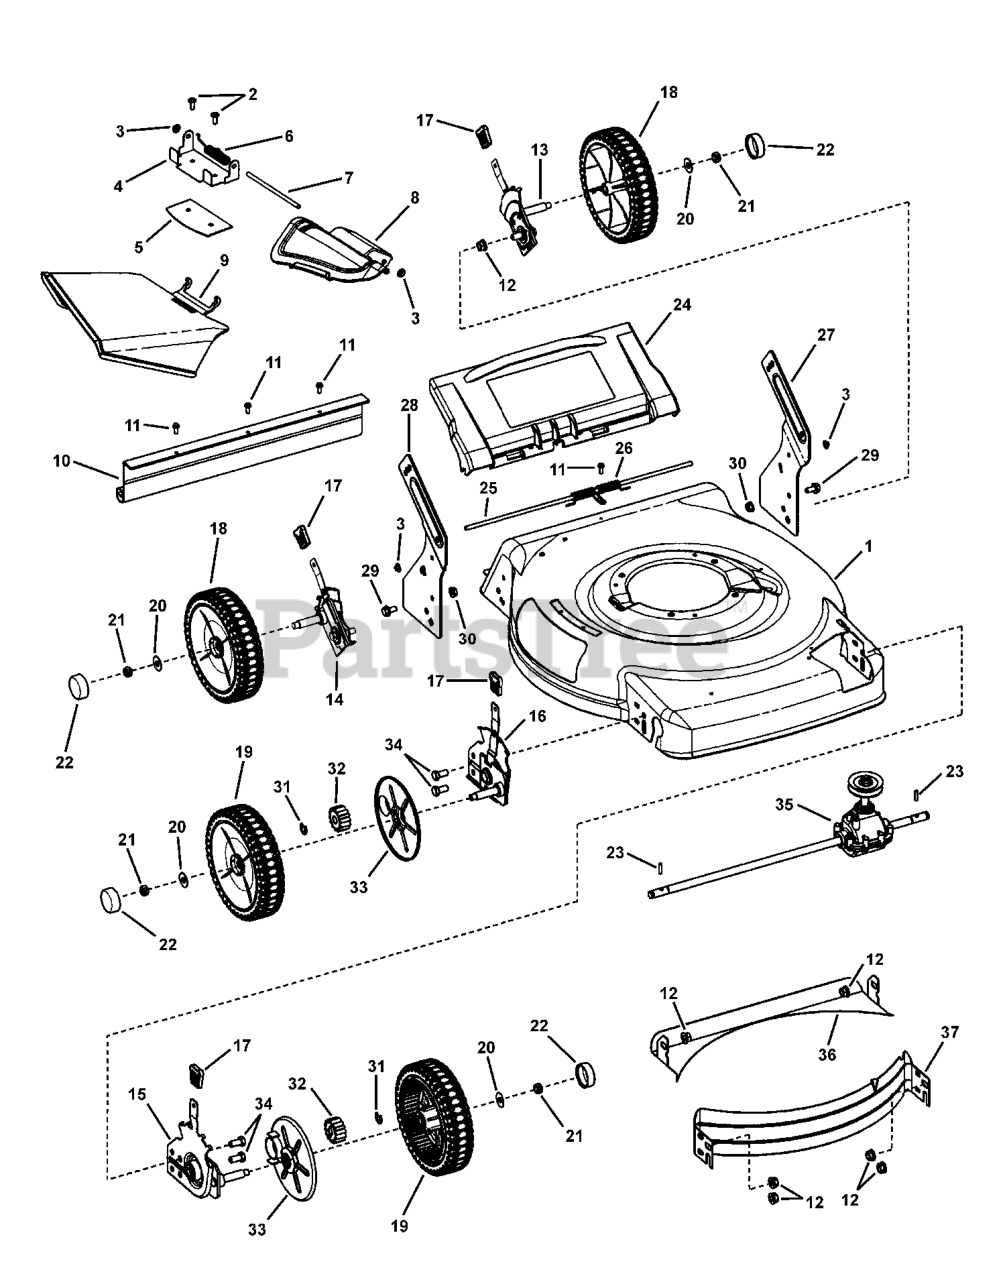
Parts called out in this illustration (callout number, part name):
1	DECK, 22" Walk, 3-N-1, Electric Start
2	SCREW, 1/4-20 x .550 Pan Head Torx (T-30)
3	PUSHNUT, 1/4"
4	BRACKET, Chute
5	PLATE, Mulch 22" RB Scotts
6	SPRING, Chute (Torsion)
7	ROD, Chute Pivot
8	COVER, Mulch, Plastic, Black
9	SIDE CHUTE, Plastic, Black
10	GUARD, Rear, 22" Mower Deck
11	SCREW, #10-24 x 1/2" Hex Washer Self-Tap (Sems)
12	NUT, 3/8-16, Hex Flange Lock GR 5
13	ASSY, Height-Of-Cut, Left Rear, 22" S.P.
14	ASSY, Height-Of-Cut, Right Rear, 22" S.P.
15	ASSY, Height-Of-Cut, Left Front, 22 S.P.
16	ASSY, Height-Of-Cut, Right Front, 22 S.P.
17	GRIP, Height Latch
18	WHEEL, 8" x 2" Idle, w/Db Tread
19	WHEEL, 8" x 2" Drive, w/Db Tread
20	WASHER, 1" O.D. x .387 I.D. Flat
21	NUT, 3/8-16 Hex Center Lock, GR 5 or B
22	HUBCAP, Round, Black
23	DRIVE PIN, 22" WBM, Front Wheel Drive
24	DOOR, 22" Rear
25	ROD, Pivot, Rear Door (1/4" Dia. X 17-1/2")
26	SPRING, Torsion, Rear Door, 22" WBM
27	BRACKET, Lower Handle, LH, 22" WBM
28	BRACKET, Lower Handle, RH, 22" WBM
29	BOLT, 5/16-18 x 5/8" Hex Flange Lock
30	NUT, 5/16-18 Hex Flange Lock, GR 5
31	RING, External Retaining
32	GEAR, Pinion, 22" WBM, Front Wheel Drive
33	DUST SHIELD, Forward, 22" WBM
34	SCREW, 3/8-16 x 3/4" Hex Head Cap, GR 5
35	TRANSMISSION, Rocker, 22" WBM, VS
36	BAFFLE, Rear, 22" Deck
37	BAFFLE, Front, 22" WBM
